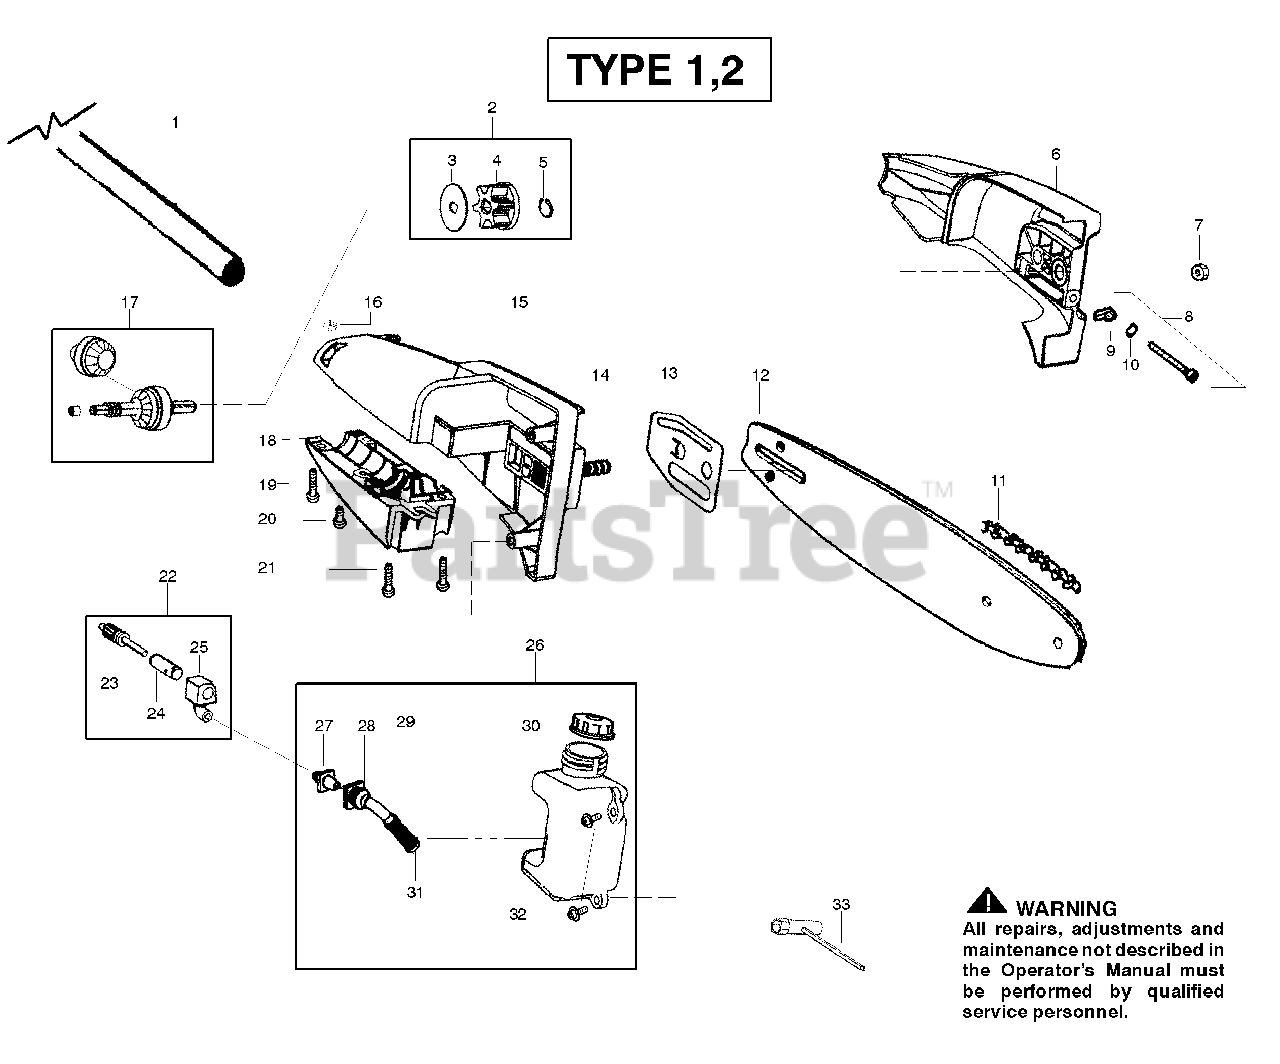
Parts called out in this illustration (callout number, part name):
1	Assy-Driveshaft
2	Kit-Sprocket Assy.
4	Sprocket
5	Retainer-Sprocket
6	Assy-Bar Clamp
7	Nut-Bar Mounting
8	Kit-Bar Adjust
9	Pin-Bar Adjust
10	Retainer-Bar Adjust
11	Accy-Chain-8"
13	Plate-Bar pad
14	Bolt-Bar
15	Hsg. -Upper
17	Kit-Gear Assy
18	Hsg.-Lower
20	Screw-Align
22	Kit-Oil Assy
23	Assy-Gear Plunger
25	Block-Oil
26	Assy-Oil Tank
27	Fitting-Oil Line
28	Intake-Oil Line
29	Filter-Oil
30	Cap-Oil
31	Plug-Oil Filter
33	Wrench-Bar
